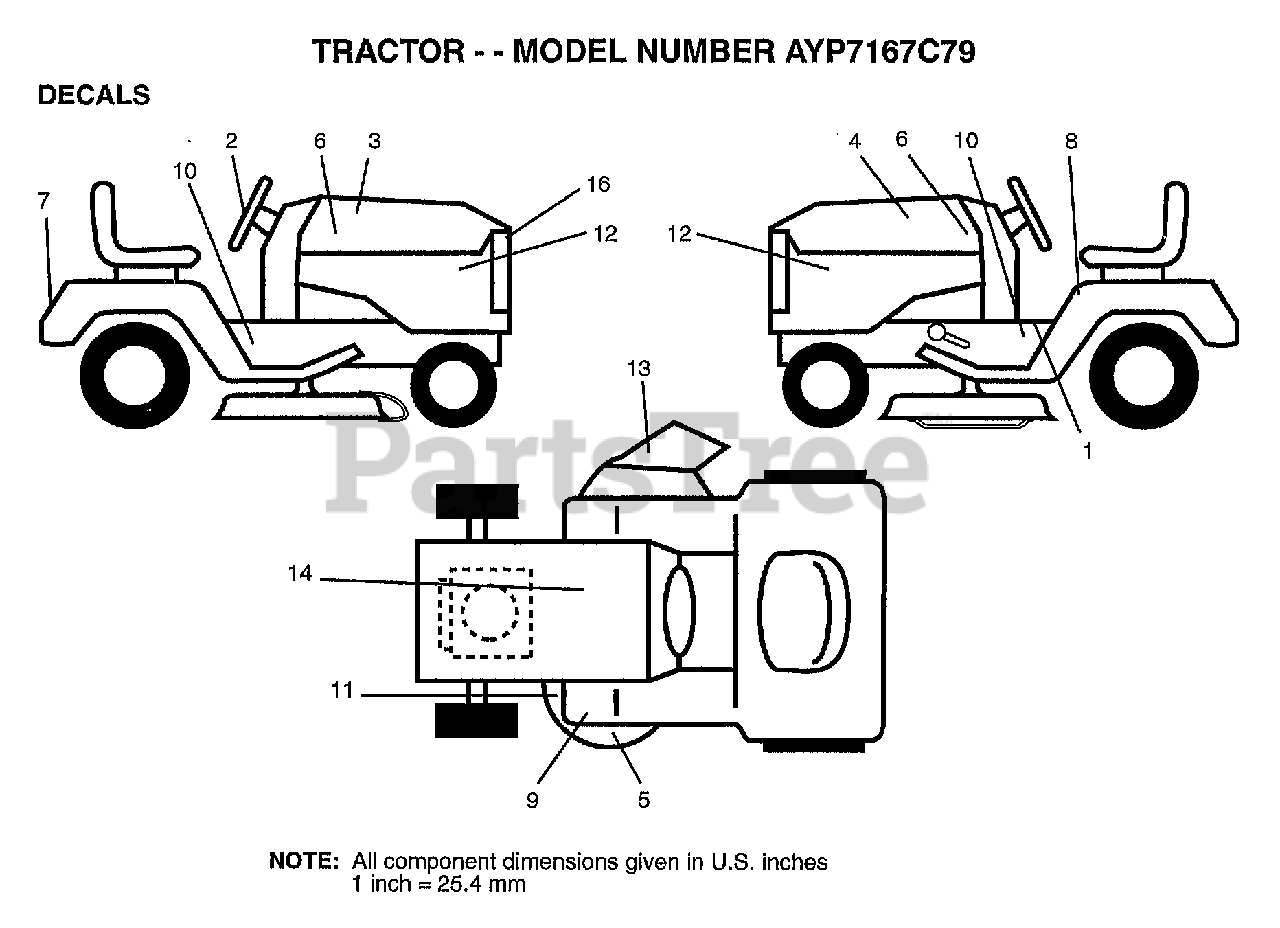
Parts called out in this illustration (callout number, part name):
1	"DECAL DASH,OPER."
2	DECAL STEER WHL
3	DECAL HOOD RH
4	DECAL HOOD LH
5	DECAL DECK WIZ +
6	NAMEPLATE.HD.WIZA
8	"DECAL DANGER,FEND"
10	DECAL CHASSIS WIZ
11	"DECAL-SCHEM,BELT"
12	"DECAL PANEL,SIDE"
13	DECAL DECK MULCH
14	DECAL.BATRY.3-3908
16	DECAL.LENS.WIZARD
